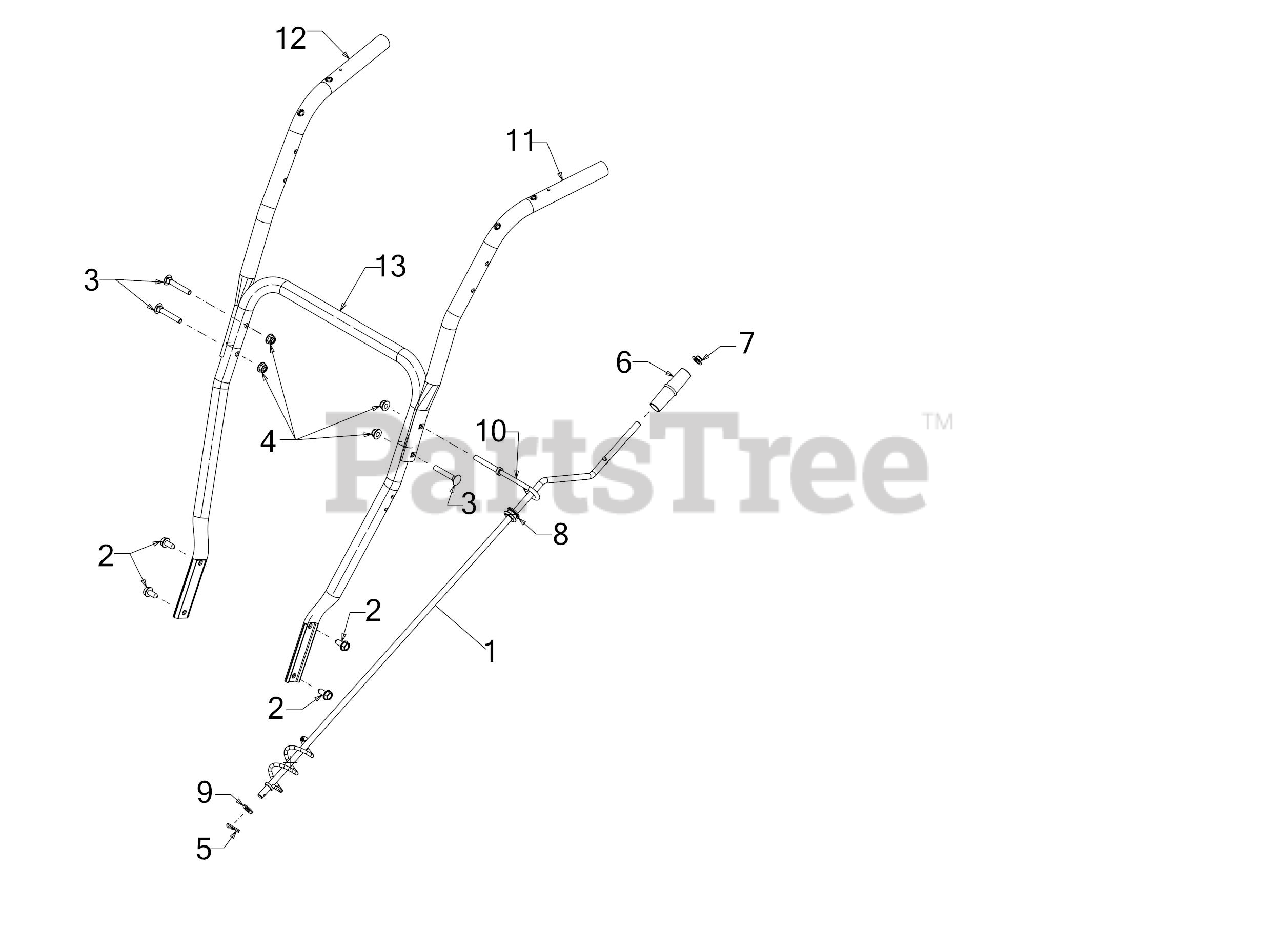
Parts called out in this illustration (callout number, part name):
1	CHUTE CRANK ASSEMBLY
2	SCREW 5/16-18 x .750
3	CARRIAGE BOLT 5/16-18 x 2.00 GR5
4	FLANGE LOCK NUT 5/16-18
5	COTTER PIN .072 DIA
6	CHUTE CRANK KNOB
7	PUSH NUT
8	GROMMET
9	FLAT WASHER
10	CHUTE CRANK EYEBOLT
11	UPPER HANDLE (LH)
12	UPPER HANDLE (RH)
13	LOWER HANDLE
